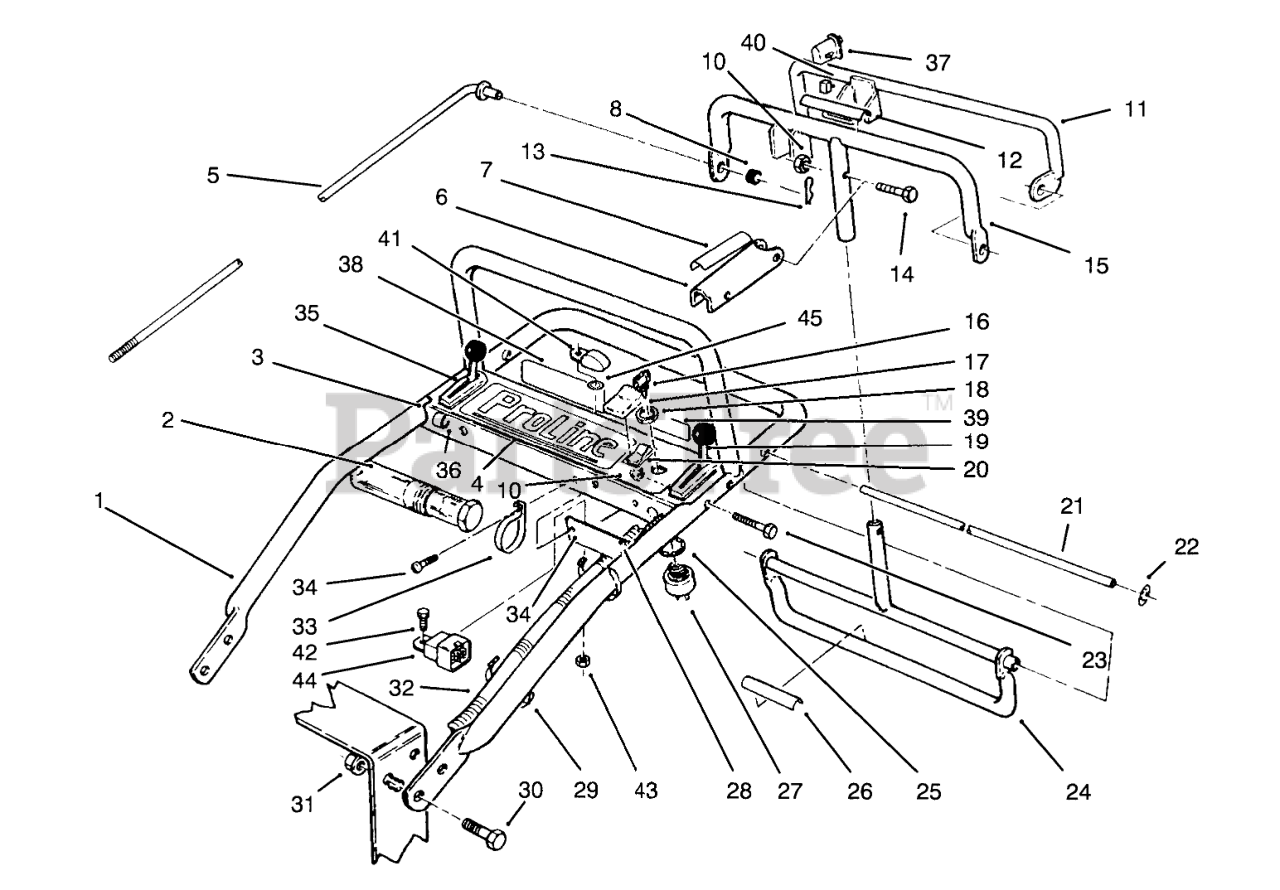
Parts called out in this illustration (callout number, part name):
1	Handle-Upper
2	TUBE-MANUAL
3	Panel-Control
4	DECAL-CNTRL PANEL-30175
5	ROD-CONTROL
6	Lever-Parking Brake
7	DECAL-LEVER, PARKING
8	GROMMET-RUBBER
10	NUT-LOCK, NI
11	Bail
12	DECAL
13	PIN-COTTER
14	SCREW-SHH
15	Bar
16	KEY-IGNITION
17	BOOT-SWITCH
18	NUT-HH
19	THROTTLE CONTROL
20	Switch-Clutch (Incl. Ref. #17)
21	PIVOT ROD
22	NUT-PUSH-ON, CIRCULAR
23	SCREW-SHH
24	Control Pivot
25	WASHER-TOOTH, INTERNAL
26	DECAL
27	Switch-Ignition (Incl. Ref. #16, 18 & 25)
28	Panel-Bottom
29	TIE-CABLE
30	SCREW-HHF
31	NUT-HF
32	WIRE HARNESS
33	CLAMP-R
34	SCREW-SHWH
35	CHOKE CONTROL
36	SPACER
37	SWITCH-BAIL
38	DECAL-INSTRUCTION, SAFETY
39	DECAL-INSTRUCTION
40	CONNECTOR-BODY
41	Module
42	SCREW-HH
43	NUT-LOCK, NI
44	RELAY
45	WASHER-LOCK/EXT
